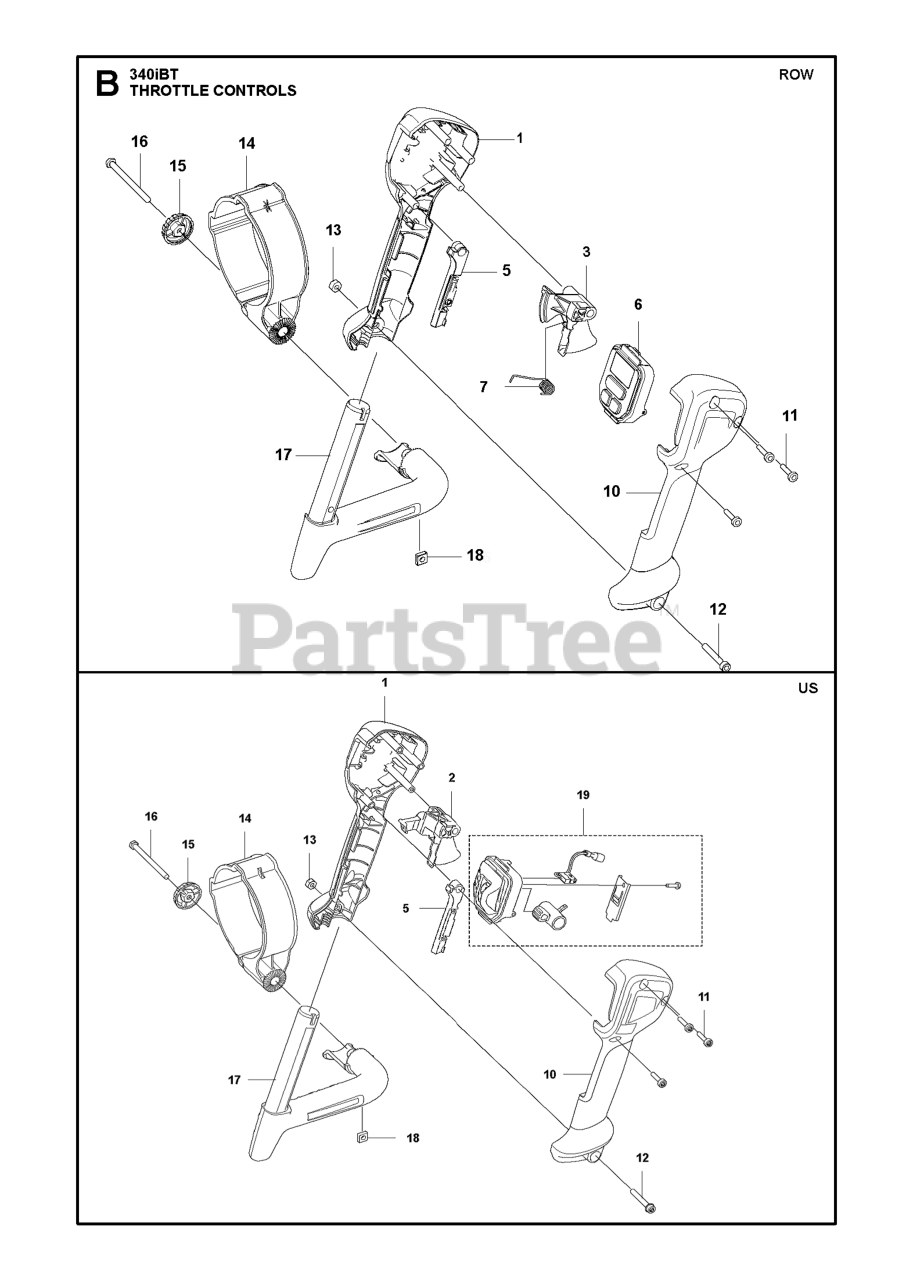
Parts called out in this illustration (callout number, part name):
2	Triggers
3	THROTTLE CONTROL ASSY
5	COVER HANDLE ESD
7	SPRING THROTTLE CONTROL
10	HANDLE HALF RIGHT
11	SCREW ITXSCT PW4.2X18 10.9 ZN
14	HANDLE HOLDER
17	HOLDER HANDLE
19	Controls
